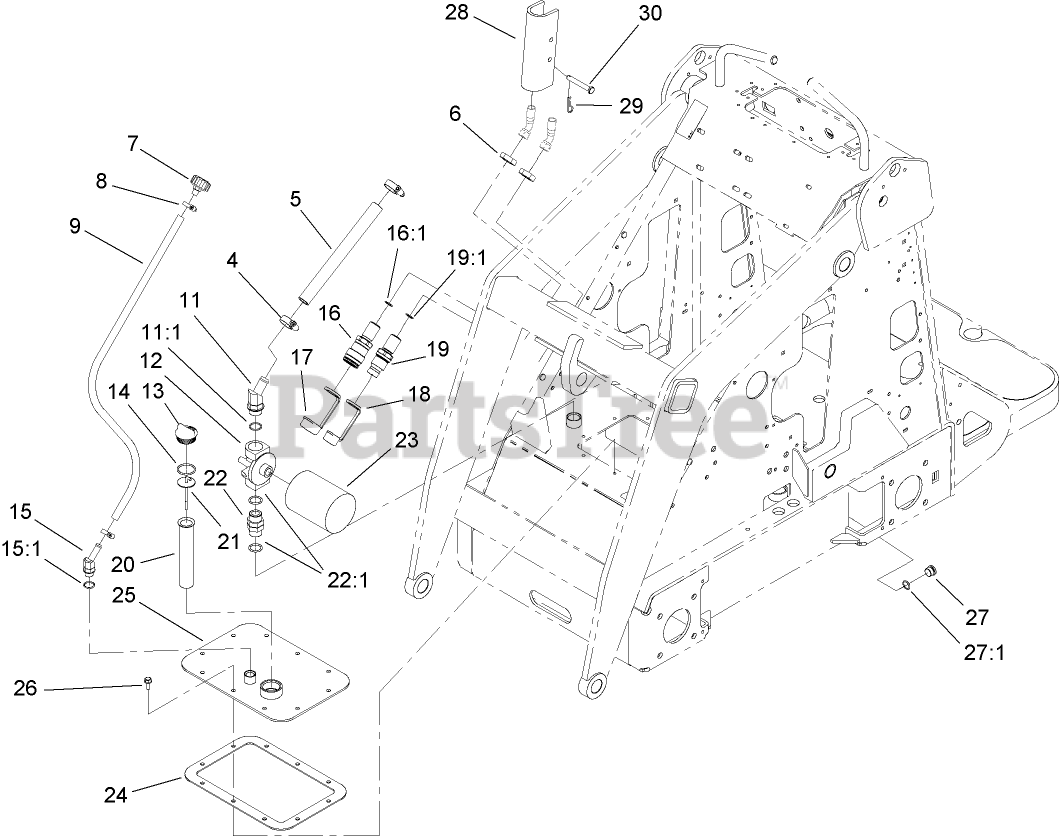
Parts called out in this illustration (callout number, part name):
4	CLAMP-HOSE
5	HOSE-HYD, SUCTION, HI
6	NUT-LOCK, BULKHEAD
7	BREATHER
8	CLAMP-HOSE
9	HOSE-VENT
11	ELBOW-45 DEG
11:1	O-RING
12	HEAD-FILTER
13	PLUG-PLASTIC
14	O-RING
15	FITTING-HYD, 45 DEG
15:1	O-RING
16	BULKHEAD COUPLER ASM
16:1	O-RING
17	CAP-DUST, COUPLER
18	CAP-DUST, NIPPLE
19	BULKHEAD NIPPLE ASM
19:1	O-RING
20	FILTER-SCREEN
21	DIPSTICK-OIL
22	FITTING-THREAD, STRAIGHT
22:1	O-RING
23	FILTER-OIL, TRANSMISSION
24	GASKET-COVER
26	SCREW
27	PLUG-HEX
27:1	O-RING
28	LOCK-CYLINDER
29	PIN-HAIR
30	PIN-CLEVIS
